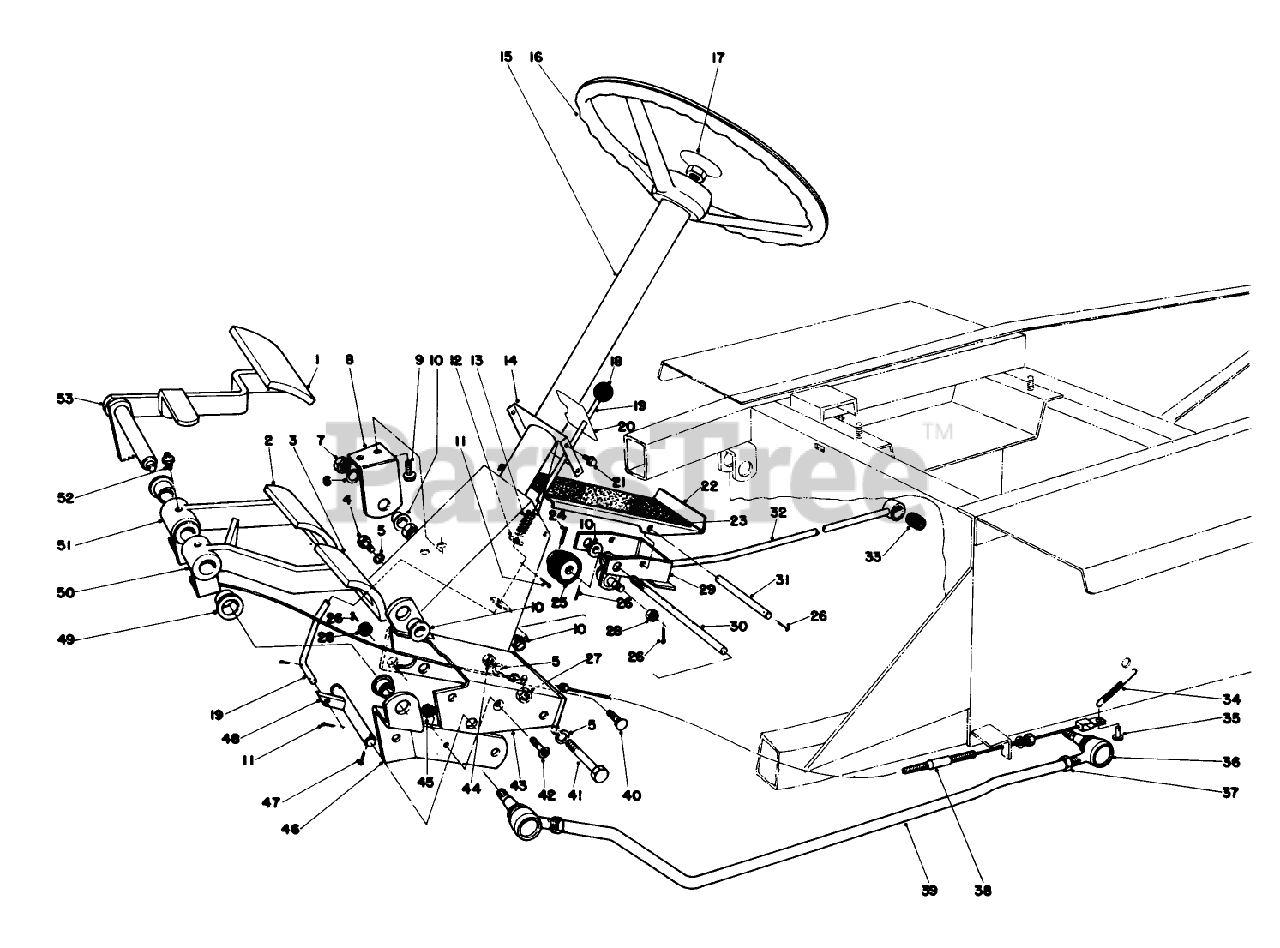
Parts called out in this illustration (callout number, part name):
1	PAD-BRAKE
2	PAD-TURN, RIGHT
3	PAD-TURN, LEFT
4	SCREW-HH
5	WASHER-LOCK
6	WASHER-FLAT
7	NUT-JAM
8	Mount-RH Pedal
9	SCREW-HWHTF
10	BUSHING-FLANGE
11	PIN-COTTER
12	WASHER-FLAT
13	Spring
14	STRG COLUMN SUPT R
15	STEERING GEAR ASM,GM72 PRE 1988
16	STEERING WHEEL
17	STEERING WHEEL CAP
19	BRAKE LATCH ROD B
20	PARKING BRAKE DECAL
21	SCREW-HWH
22	TRACTION PEDAL R
23	TRACTION PEDAL PAD
24	PIN-SPRING
25	FRICTION WHEEL ASM
26	PIN-COTTER
27	NUT-HEX
28	NUT-SLOTTED
29	Pivot Bracket (Incl. Ref. #10)
30	TRACT PEDAL SHAFT
31	TRACT PEDAL PIN
32	PUMP CONTROL TUBE WA
33	BUSHING-RUBBER
34	SPRING-EXTENSION
35	PIN-CLEVIS
36	Socket Ass-y. (Incl. Ref. #28)
37	NUT-JAM
38	LH BRAKE CABLE ASM
39	FRT STRG TUBE PP
40	SCREW-CARR
41	SCREW-HH
42	SCREW-HSFH
43	Brake Mount
44	NUT-HEX
45	NUT-KEPS
46	Brake Pivot Shaft Mount
47	PIN-COTTER
48	Brake Latch Shaft
49	BUSHING-FLANGE
50	Brake Pedal L.H. (Incl. Ref. #49)
51	Brake Pedal R.H. (Incl. Ref. #49)
52	FITTING-GREASE
53	Pedal-Parking Bake
